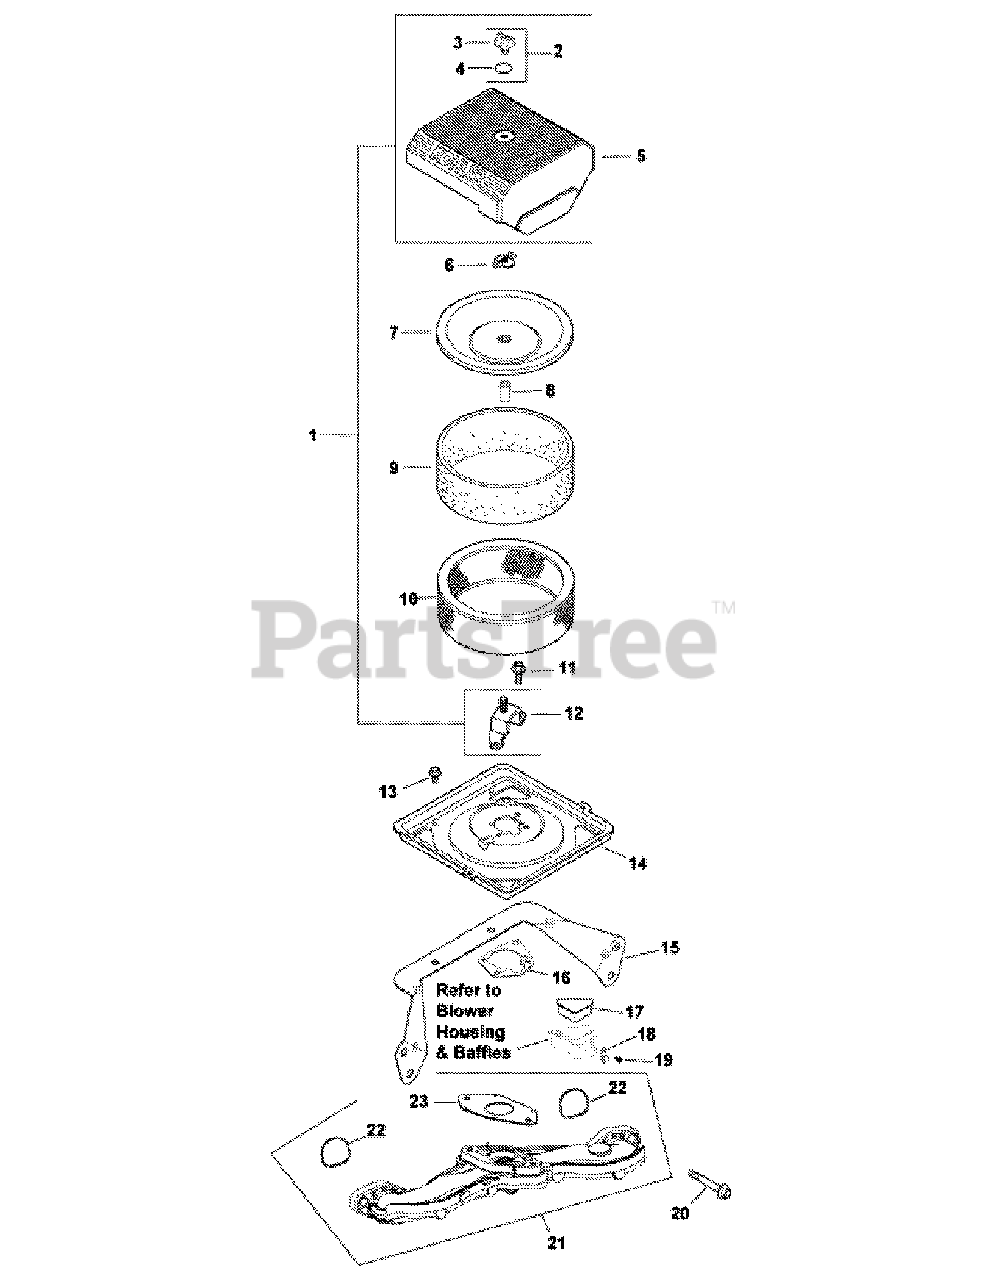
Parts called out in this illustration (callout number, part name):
1	Kit, Air Cleaner Cover (Includes 2-5,12)
2	Kit, Knob W/Seal(Includes 3,4)
5	Cover, Air Cleaner
7	Cover, Inner Air Cleaner
8	Seal, Inner Air Cleaner
9	Element, Precleaner
10	Filter Element, Air Cleaner & Precleaner (Low)
11	Screw, Flg Thd Frm M6X1.0X16
12	Bracket, Air Cleaner
13	Screw, Flg Thd Frm M5X.8X10
14	Base, Air Cleaner
15	Bracket, Air Cleaner Base
16	Gasket, Air Cleaner Base
17	Cover, Blower Housing
19	Screw, Wsh Hd Tap #8-18X1/2"
20	Screw, Flg M6X1.0X40
21	Kit, Intake Manifold (Includes 21,22)
22	O-Ring, Intake Port
23	Gasket, Carburetor
